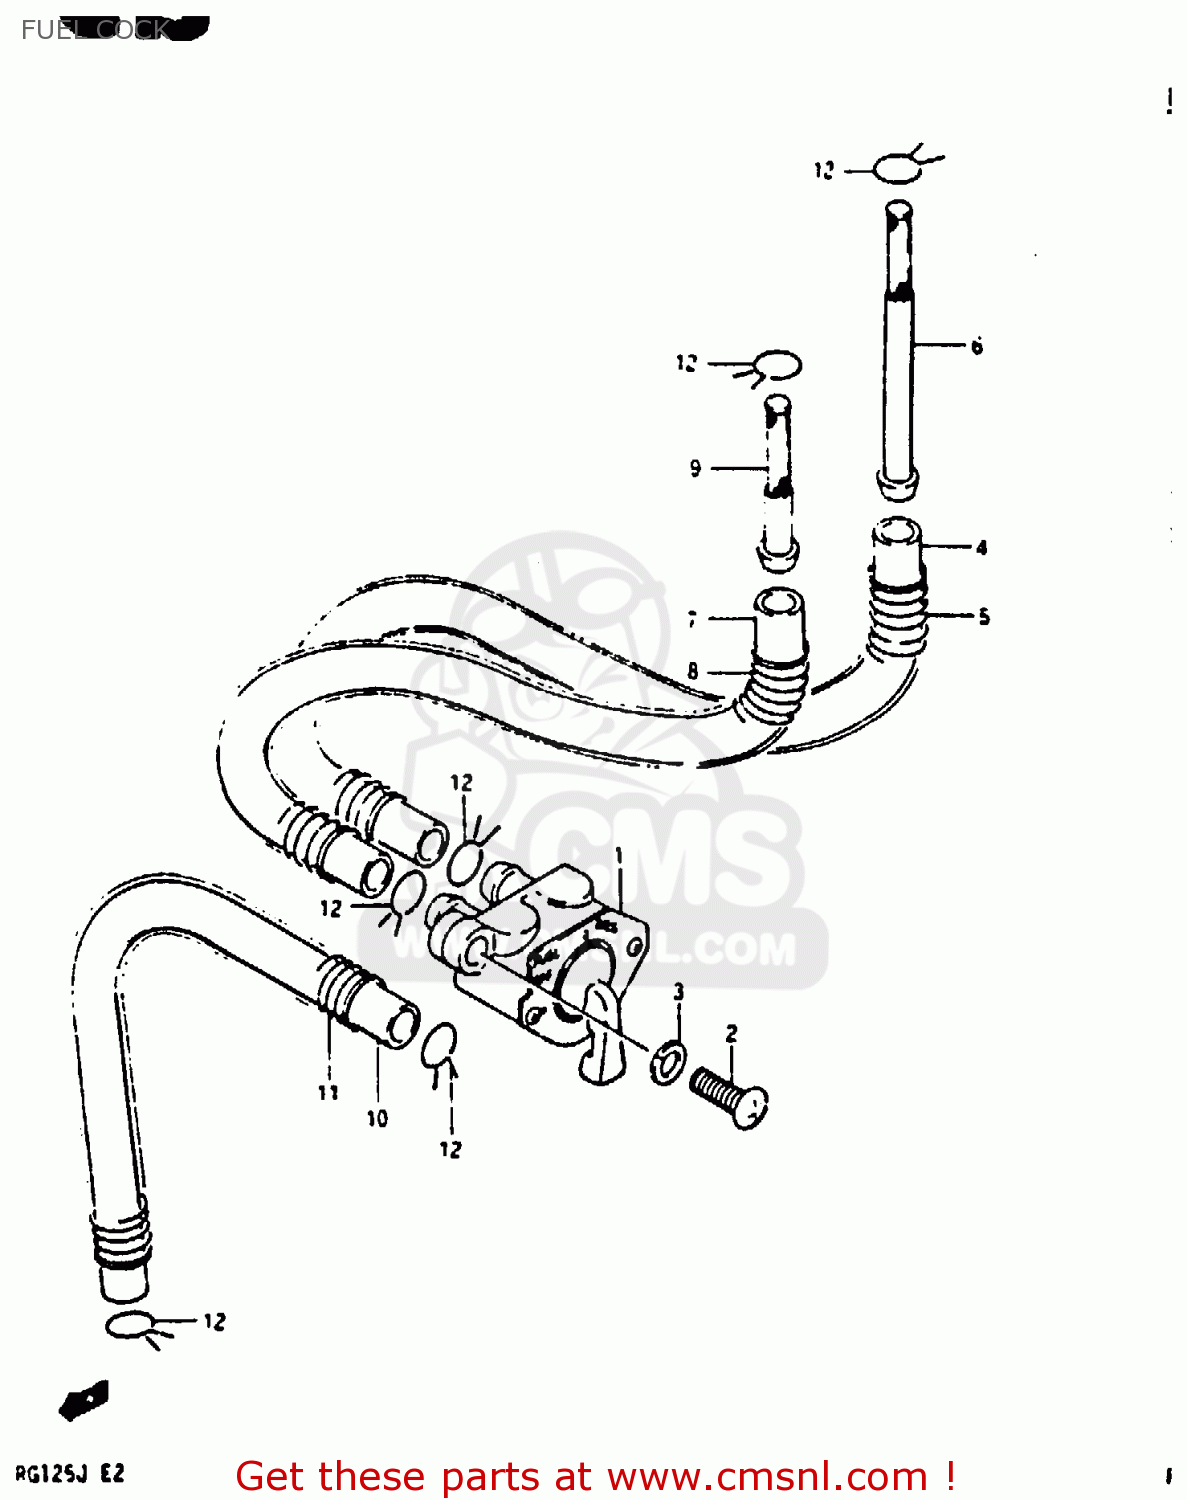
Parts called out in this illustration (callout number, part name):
1	COCK ASSY,FUEL
2	SCREW
3	LOCK WASHER
4	HOSE
5	SPRING
6	FILTER,FUEL
7	HOSE 7X10.2X210
8	SPRING
9	FILTER,FUEL
10	HOSE
11	SPRING
12	CLIP
